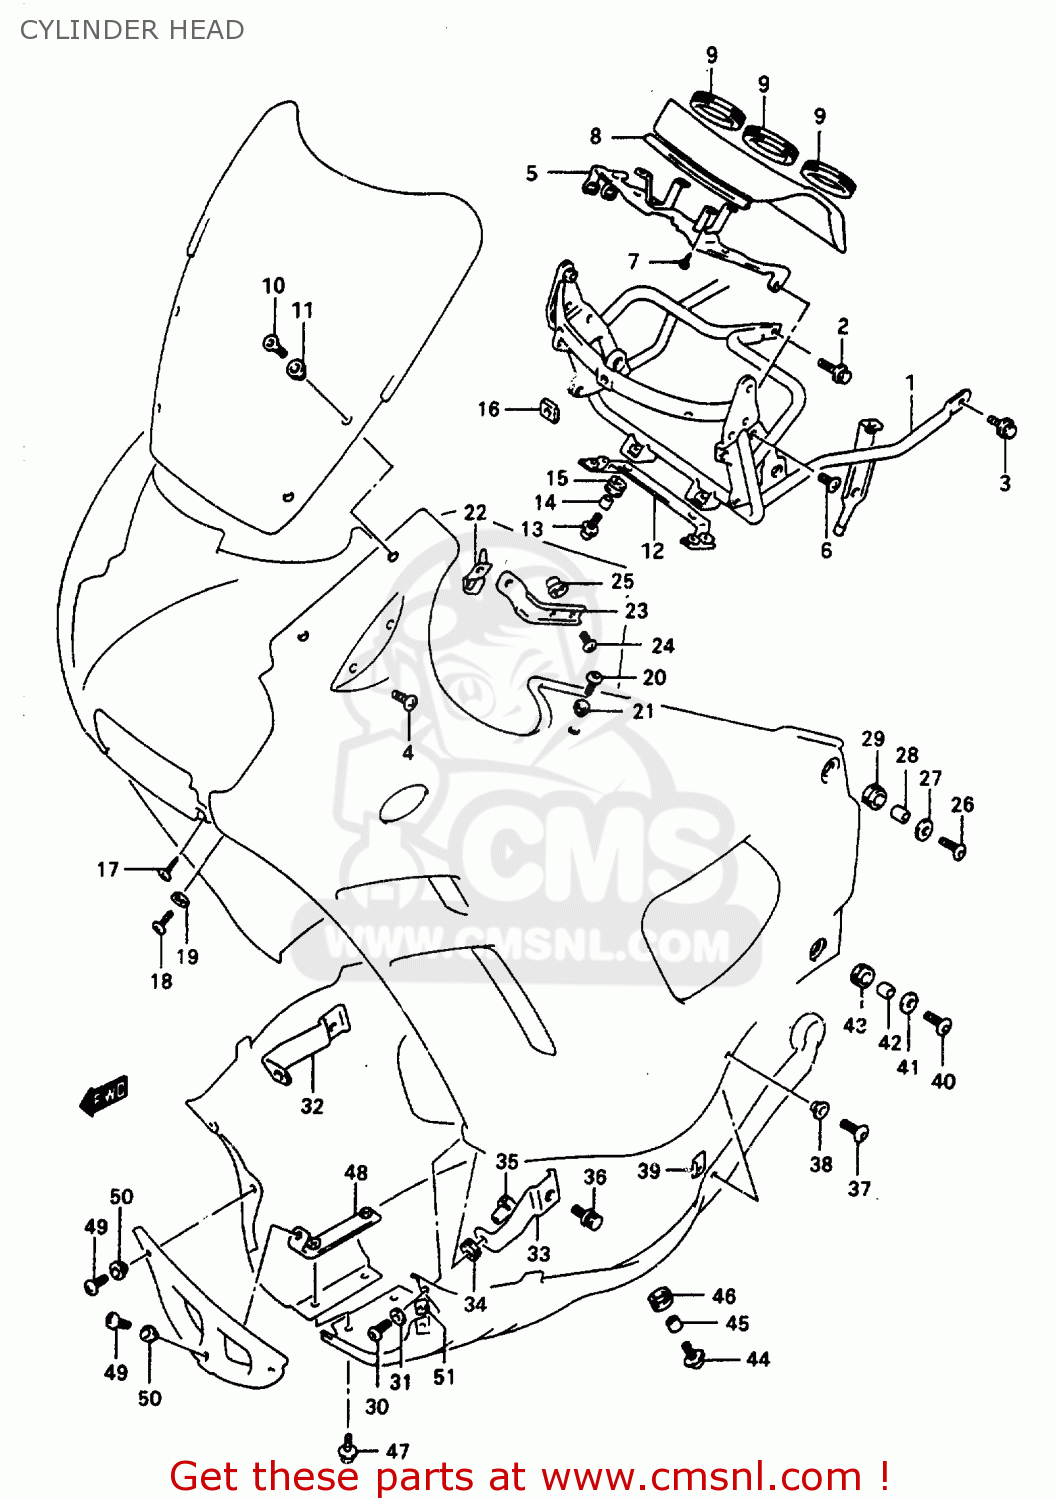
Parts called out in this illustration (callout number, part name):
1	HEAD ASSEMBLY,CYLINDER
2	GUIDE,VALVE
3	RING,SNAP
4	BOLT(6X39)
5	PIN(6.2X8X11)
6	GASKET,CYLINDER HEAD (NAS)
7	O RING(D:2.6,ID:12.1)
8	PIN
9	BOLT
10	NUT
11	NUT
12	GASKET(10.2X20X2).3 (NAS)
13	WASHER (10.5X22X2.3)
14	PIPE,OIL NO.1
15	PIPE,OIL NO.3
16	PLATE,OIL PIPE,R
17	PLATE,OIL PIPE,L
18	BOLT
19	PLUG,SPARK(CR9EK)
20	PIPE ASSY,INTAKE NO.1
21	PIPE ASSY,INTAKE NO.2
22	PIPE ASSY,INTAKE NO.3
23	PIPE ASSY,INTAKE NO.4
24	O RING(D:2.4,ID:39.7)
25	CLAMP
26	SCREW
27	PLUG
28	GASKET(13.8X18.8X4.8) (NAS)
